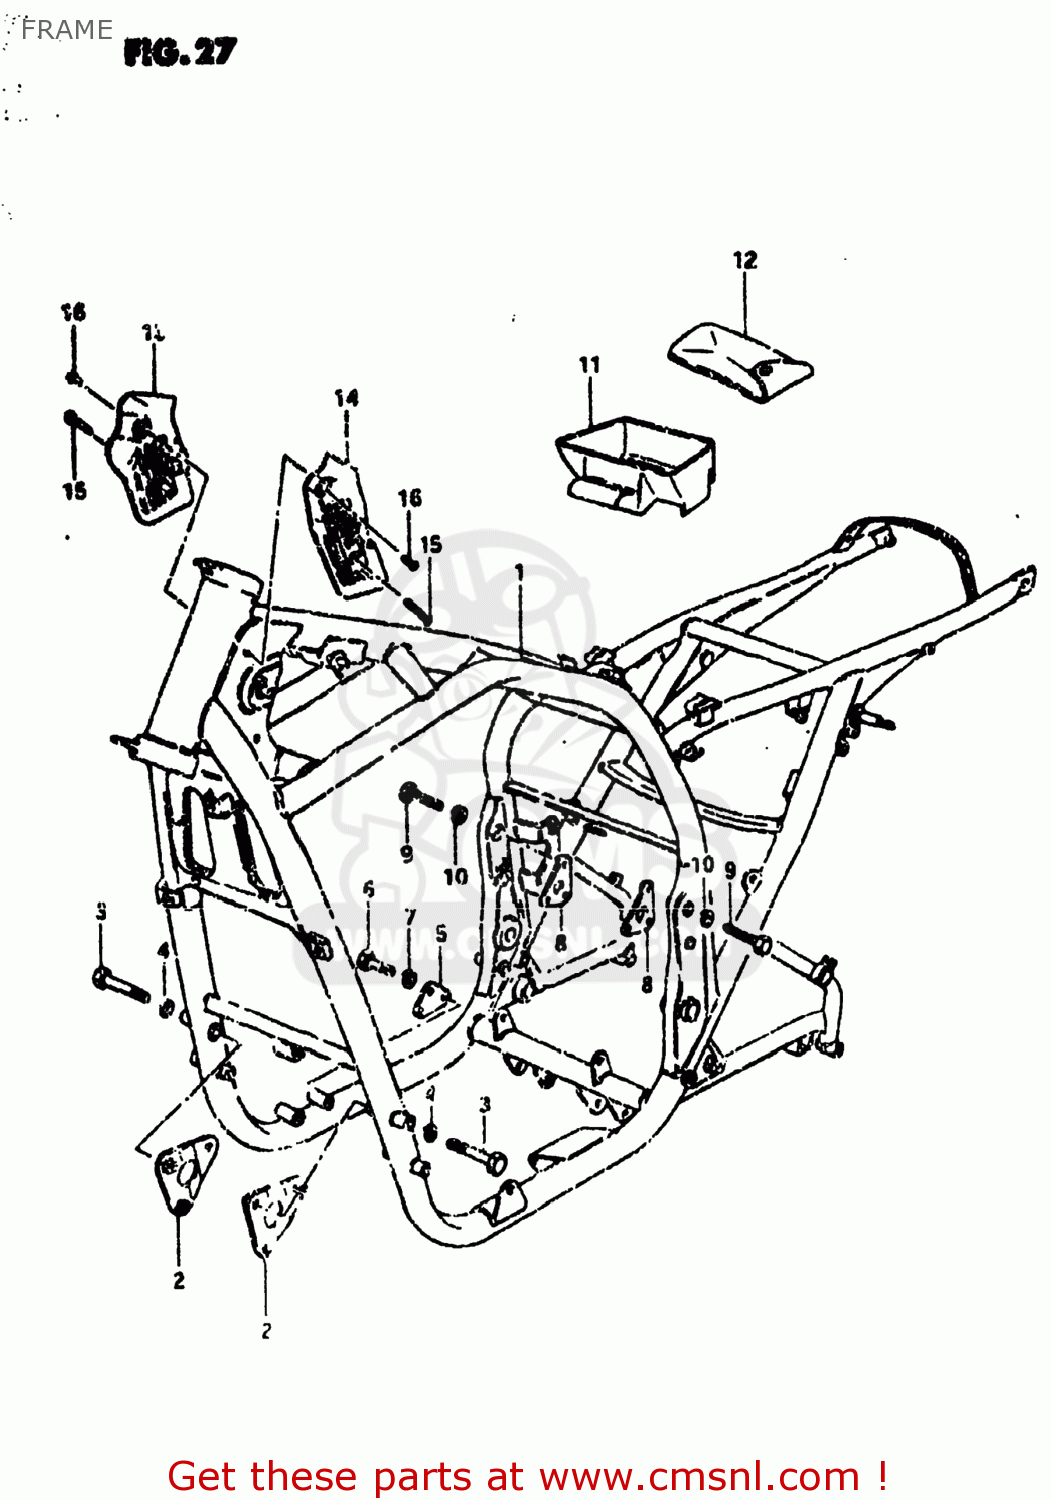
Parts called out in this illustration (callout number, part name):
1	FRAME
2	PLATE,ENG MTG NO.1
3	BOLT
4	LOCK WASHER
5	PLATE,ENGINE MOUNTING
6	BOLT
7	LOCK WASHER
8	PLATE,ENGINE MOUNTING
9	BOLT
10	LOCK WASHER
11	HOLDER,TOOL
12	TOOL SET
13	COVER,FRAME HEAD,RIGHT
14	COVER,FRAME HEAD,LEFT
15	SCREW, LOWER
16	SCREW
